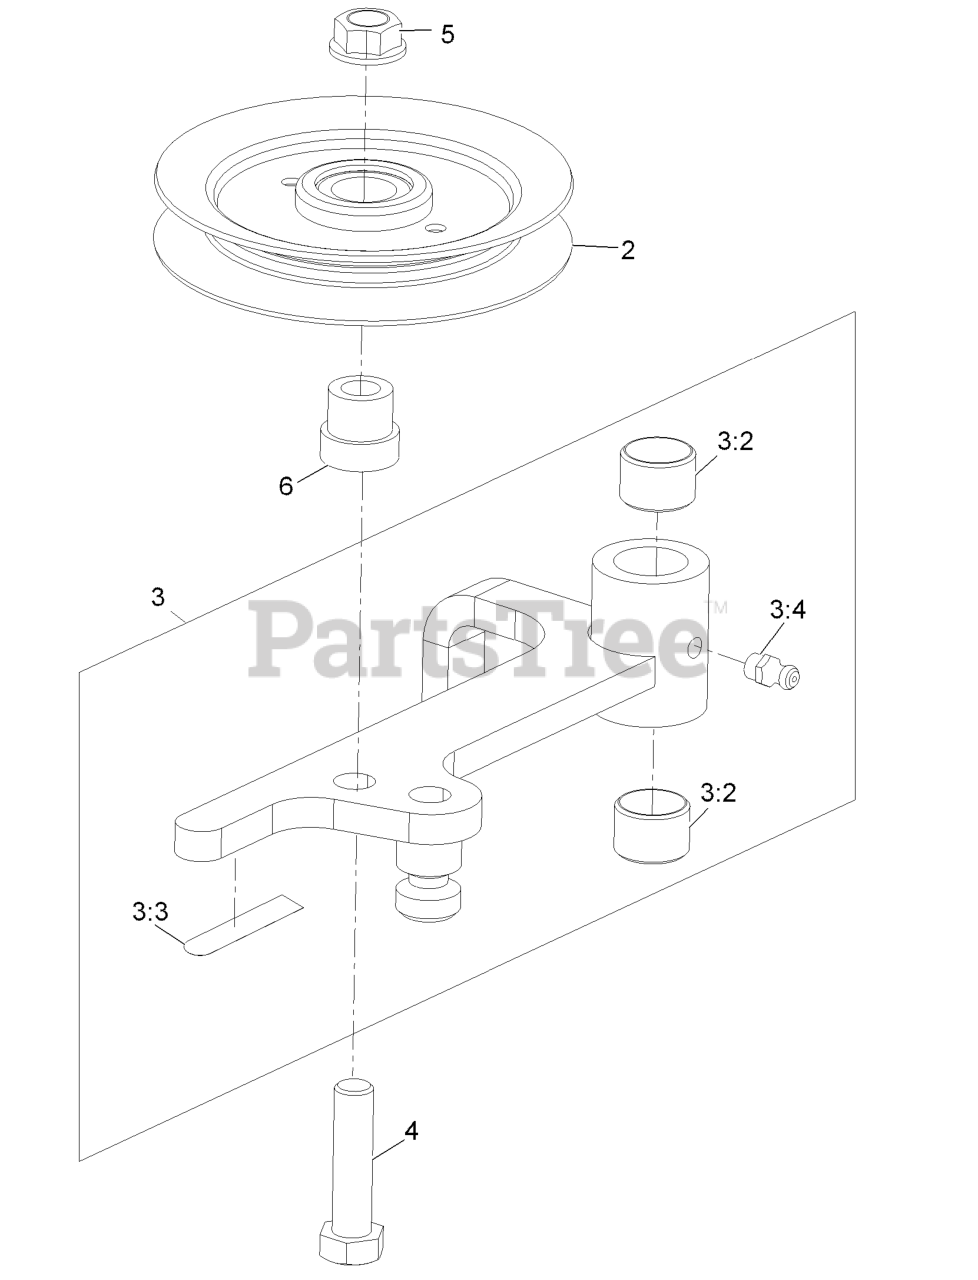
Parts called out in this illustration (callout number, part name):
2	Idler, Flat
3	Idler Assy With Bushings
3:2	Bushing
3:3	Decal-Warning
3:4	Fitting-Grease
4	Screw-HH
5	Nut-HHF, Whiz
6	Hub, Spacer
